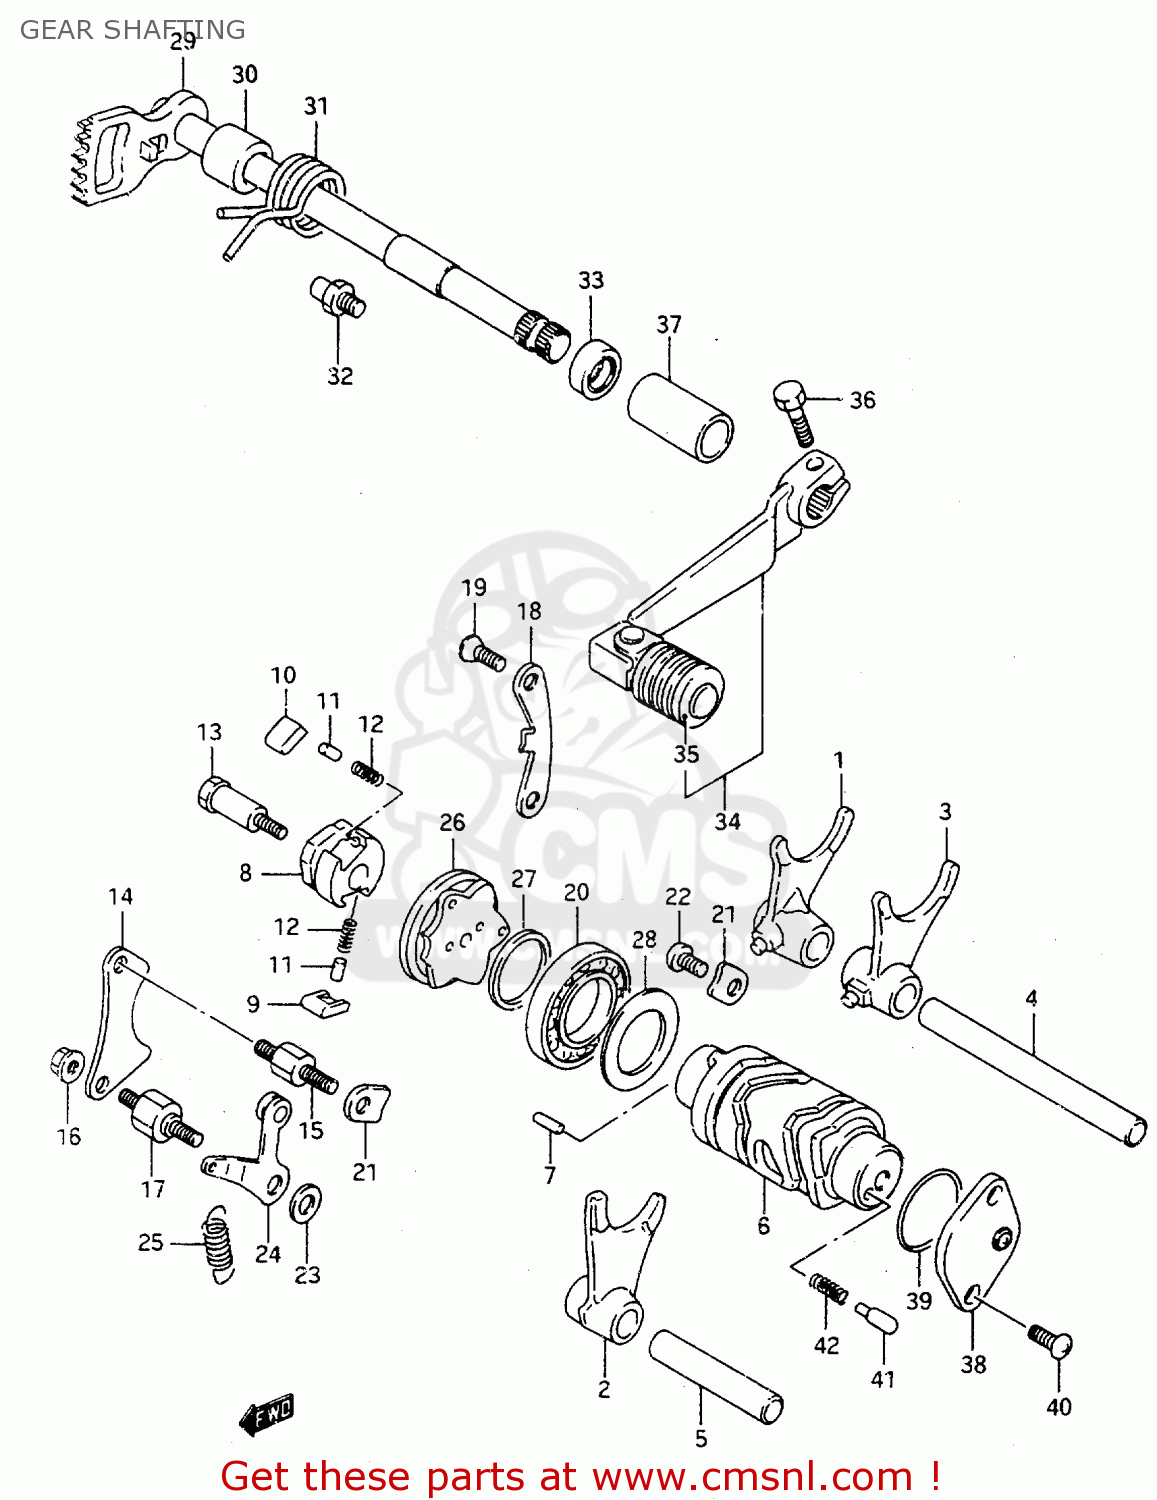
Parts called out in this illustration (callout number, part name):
1	FORK,GEAR SHIFT NO.1
2	FORK,GEAR SHIFT NO.2
3	FORK, NO. 3
4	SHAFT,GEAR SHIFT FORK
5	SHAFT,GEAR SHIFT FORK
6	CAM
7	PIN
8	GEAR,GEARSHIFT CAM DRIVE
9	PAWL,GEAR SHIFT NO.1
10	PAWL,GEAR SHIFT NO.2
11	PIN(5X8)
12	SPRING
13	PIN,SHIFT CAM DRIVEN GEAR
14	LIFTER,GEAR SHIFT POLE
15	BOSS,SHIFT PAWL LIFTER
16	NUT
17	SUPPORT,CAM STOPPER ARM
18	GUIDE,GEAR SHIFT CAM
19	SCREW
20	BEARING
21	RETAINER,GEAR SHIFT CAM BRG
22	SCREW 6X12
23	WASHER
24	STOPPER, CAM
25	SPRING
26	PLATE,GEAR SHIFT CAM
27	WASHER(25X32X3)
28	SEAL,SHIFT CAM OIL
29	SHAFT,GEAR SHIFT
30	SPACER(12X20X15.3)
31	SPRING
32	STOPPER,GEAR SHIFT ARM
33	OIL SEAL
34	LEVER ASSY,GEAR SHIFT
35	RUBBER,GEAR SHIFT PEDAL
36	BOLT
37	CUSHION
38	BODY,GEAR SHIFT SWITCH
39	O-RING (D:2.4 ID:26.2)
40	SCREW
41	PIN(5X15.5)
42	SPRING
